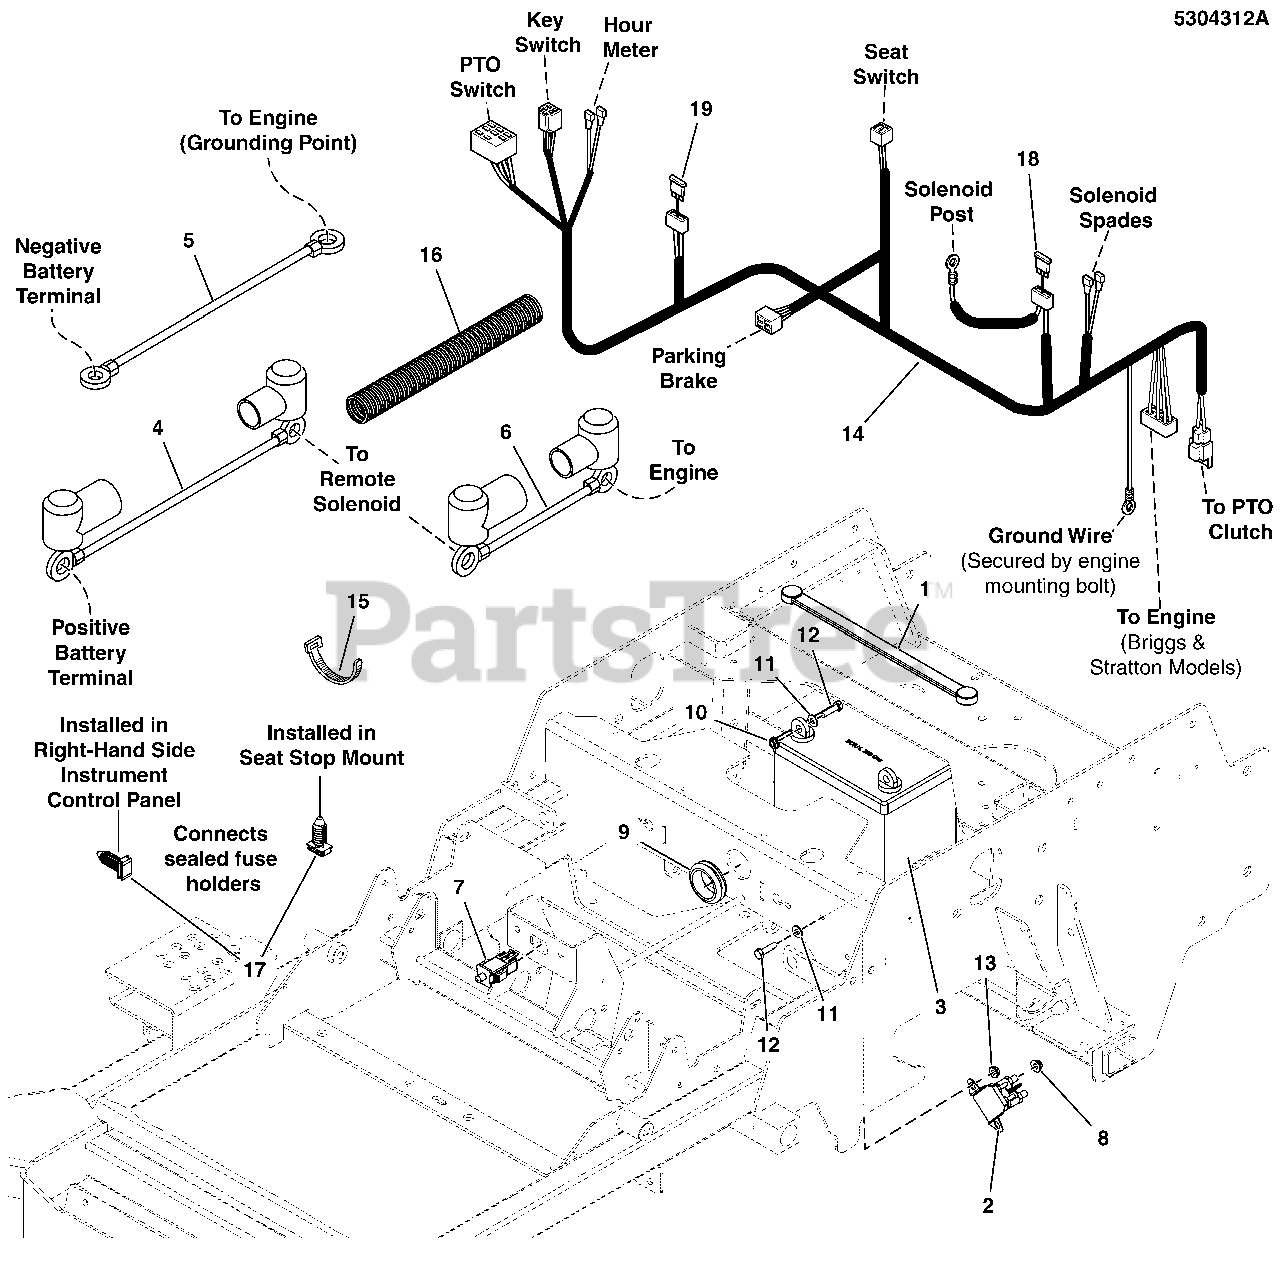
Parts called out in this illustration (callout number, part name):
1	STRAP-BLACK RUBB
2	SOLENOID, STD-BRACKET, 2-SPADE
3	BATTERY, MNTNCE FREE, 300CCA 9 PLTS WET
4	BATTERY CABLE, POS, 22, 1/4-5/16
5	BATTERY CABLE, NEG, 14, 5/16-13/32
6	BATTERY CABLE, POS, 22, 1/4-5/16
7	SWITCH, DP NO/NC SNAP-IN
8	NUT,1/4-20,KEPS,CONICAL WSHR,ZC/CL
9	GROMMET, 1-1/2" ID FOR 1/4" METAL
10	NUT, 1/4-20 HEX SERR. FLANGE
11	WASHER, 1/4 SAE
12	BOLT, 1/4-20 X 3/4 GD5 CZ
13	NUT, 1/4-20 HEX NYLOCK FLANGE
14	WIRE HARNESS, CONTENDER
15	TIE, SELF-LOCKING, 12"
16	WIRE LOOM, 3/8 ID X 18 IN
17	FIR TREE MOUNT, PACKARD
18	FUSE, ATO, 20 AMP (SV)
19	FUSE, ATO, 15 AMP (SV)
